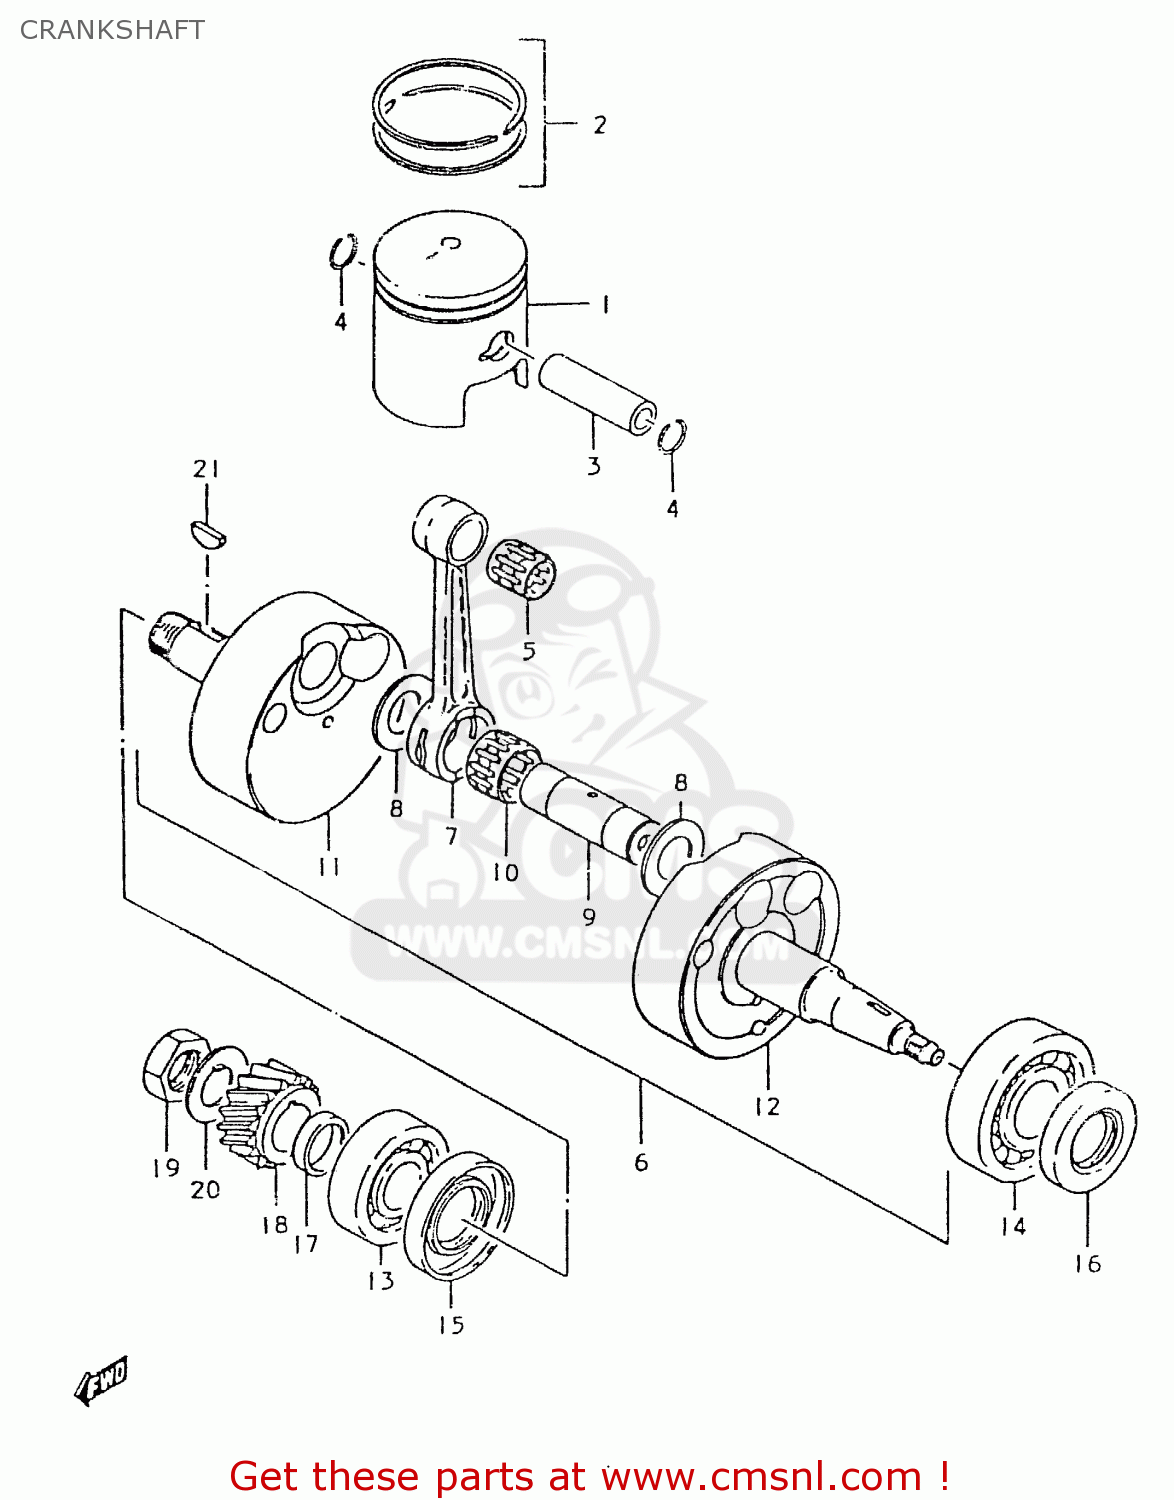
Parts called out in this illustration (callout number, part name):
1	PISTON
2	RING SET,PISTON
3	PIN,PISTON
4	RING,SNAP 14MM
5	BEARING
6	CRANKSHAFT ASSEMBLY
7	CONNECTING ROD
8	WASHER(19X32X1)
9	PIN,CRANK
10	BEARING(19X25X16)
11	CRANKSHAFT,R
12	CRANKSHAFT,LEFT
13	BEARING
14	BEARING(25X62X17)
15	SEAL,OIL(26X52X8)
16	SEAL,OIL(25X44X7)
17	SPACER(20X28X7)
18	GEAR,PRIMARY DRIVE
19	NUT
20	WASHER
21	KEY
